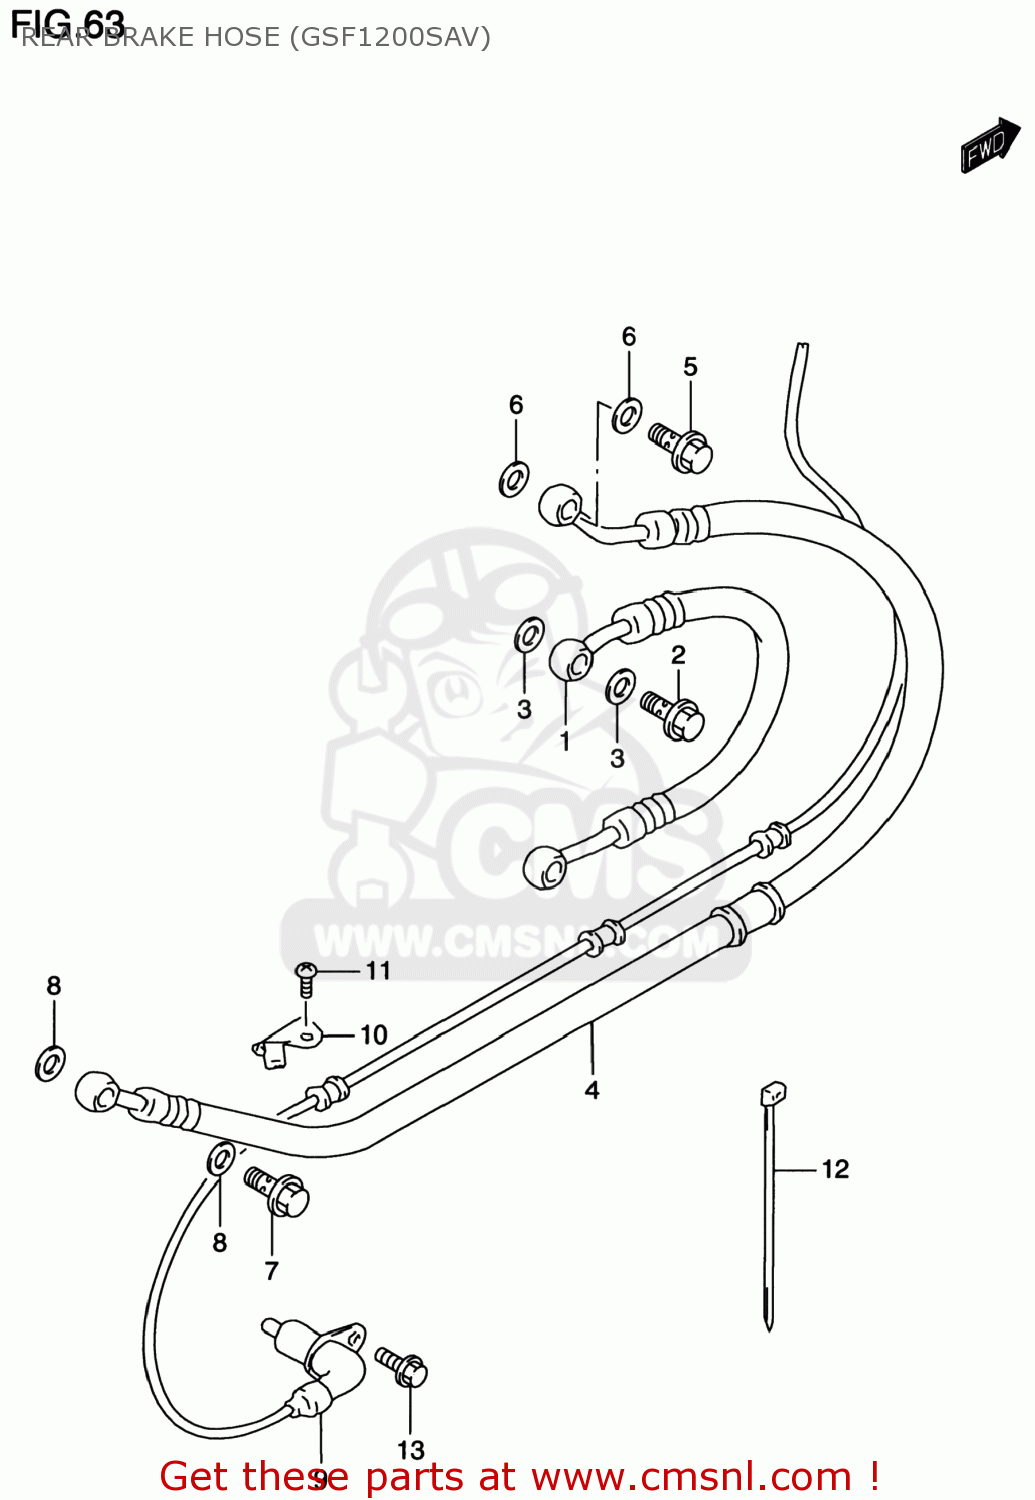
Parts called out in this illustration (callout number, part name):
1	HOSE,RR BRAKE HU IN
2	BOLT UNION
3	WASHER(10X15X1.5)
4	HOSE,RR BRAKE HU OUT
5	BOLT UNION
6	WASHER(10X15X1.5)
7	BOLT UNION
8	WASHER(10X15X1.5)
9	SENSOR,RR WHEEL ABS
10	CLAMP,ABS SENSOR RR
11	SCREW 6X10
12	CLAMP(L:145)
13	BOLT
